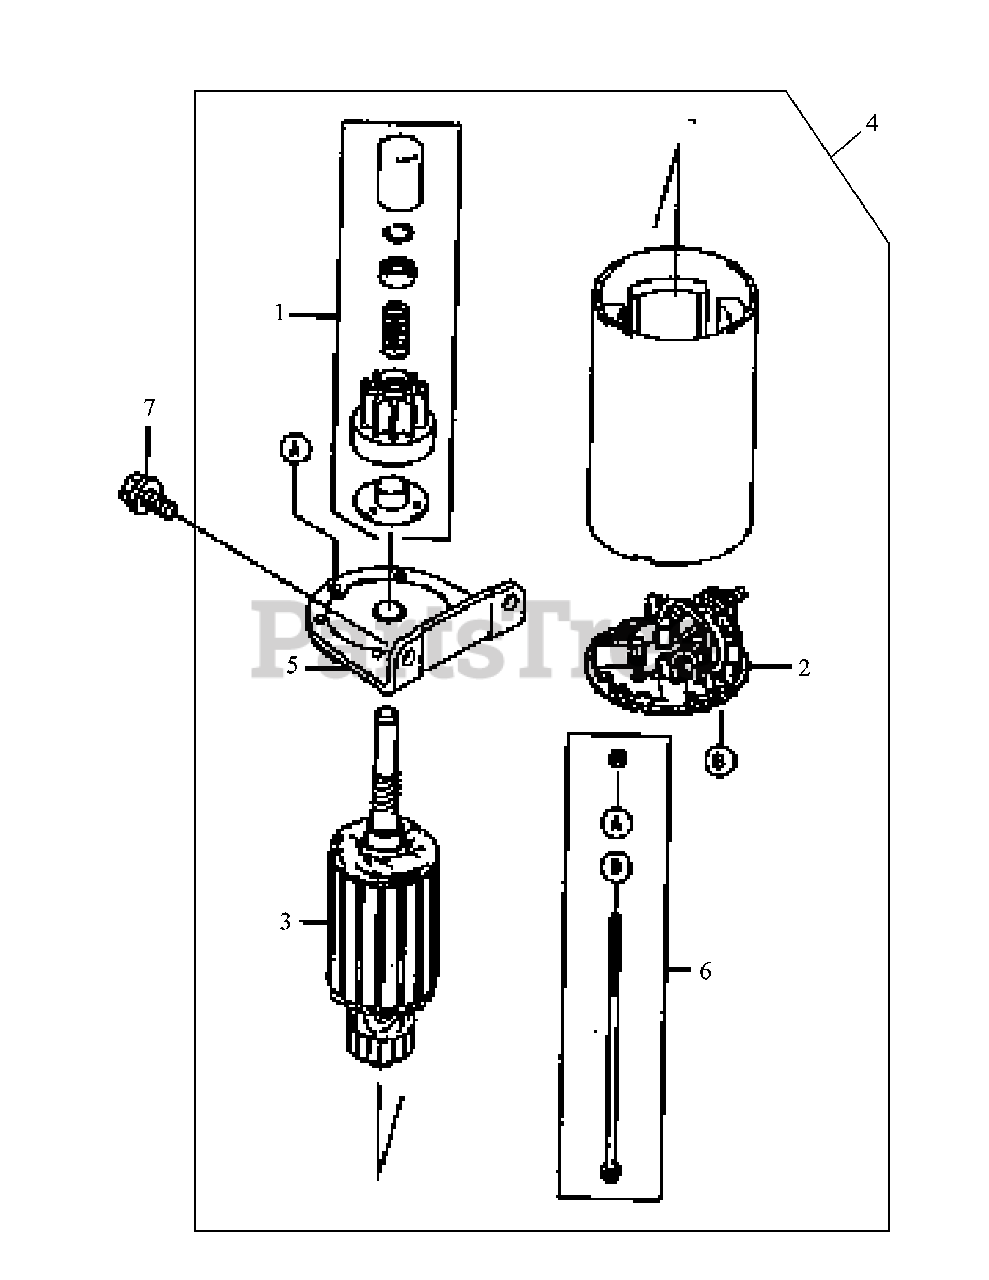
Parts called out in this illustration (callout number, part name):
1	Gear Assembly
4	Starter-Electric
5	Bracket-Assembly
